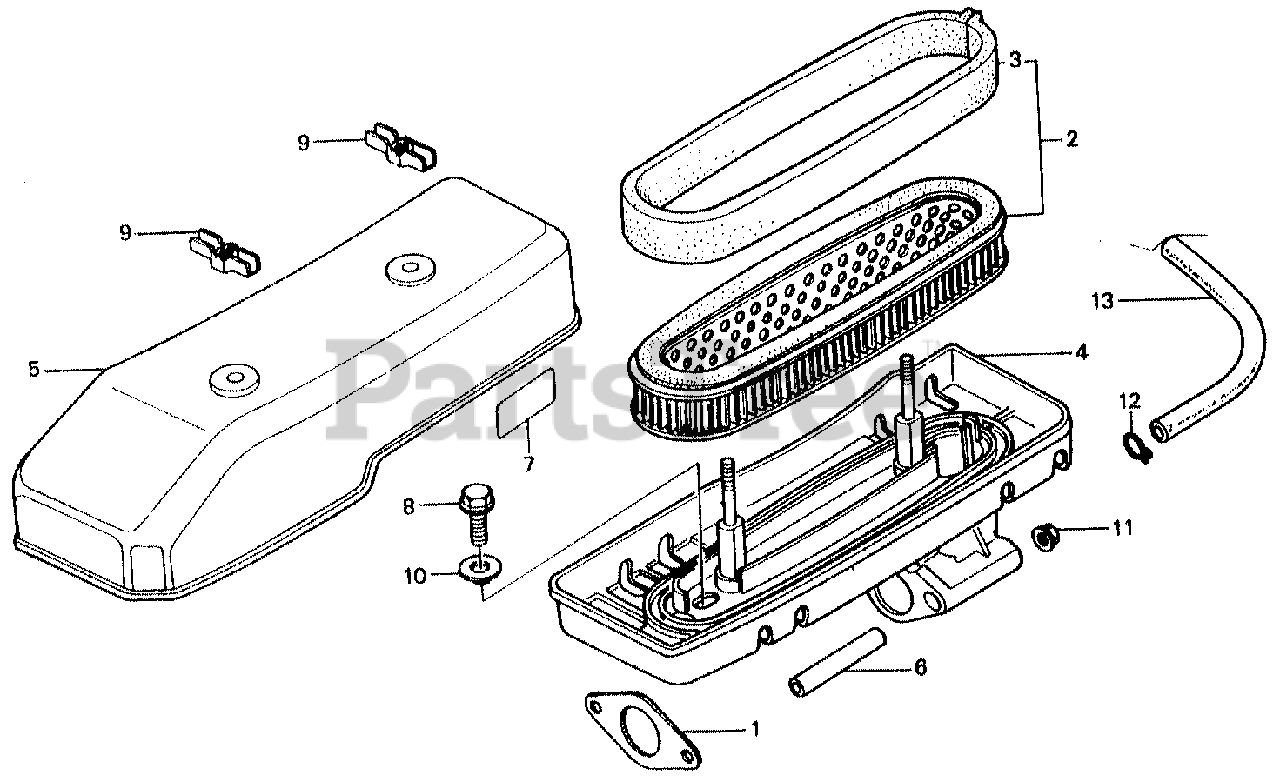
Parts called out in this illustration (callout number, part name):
1	GASKET, AIR CLEANER
2	ELEMENT, AIR CLEANER
3	FILTER (OUTER)
4	HOUSING, AIR CLEANER
5	COVER, AIR CLEANER *NH1* (BLACK)
6	COLLAR, AIR CLEANER HOUSING
7	MARK, AIR CLEANER CAUTION
8	BOLT, FLANGE (6X12) (CT200)
9	WINGNUT, AIR CLEANER COVER
10	WASHER, HEADLIGHT CASE
11	NUT, FLANGE (6MM)
12	CLIP, TUBE (B12.5)
13	BULK HOSE, VACUUM (7.3X1000) (7.5X160)
